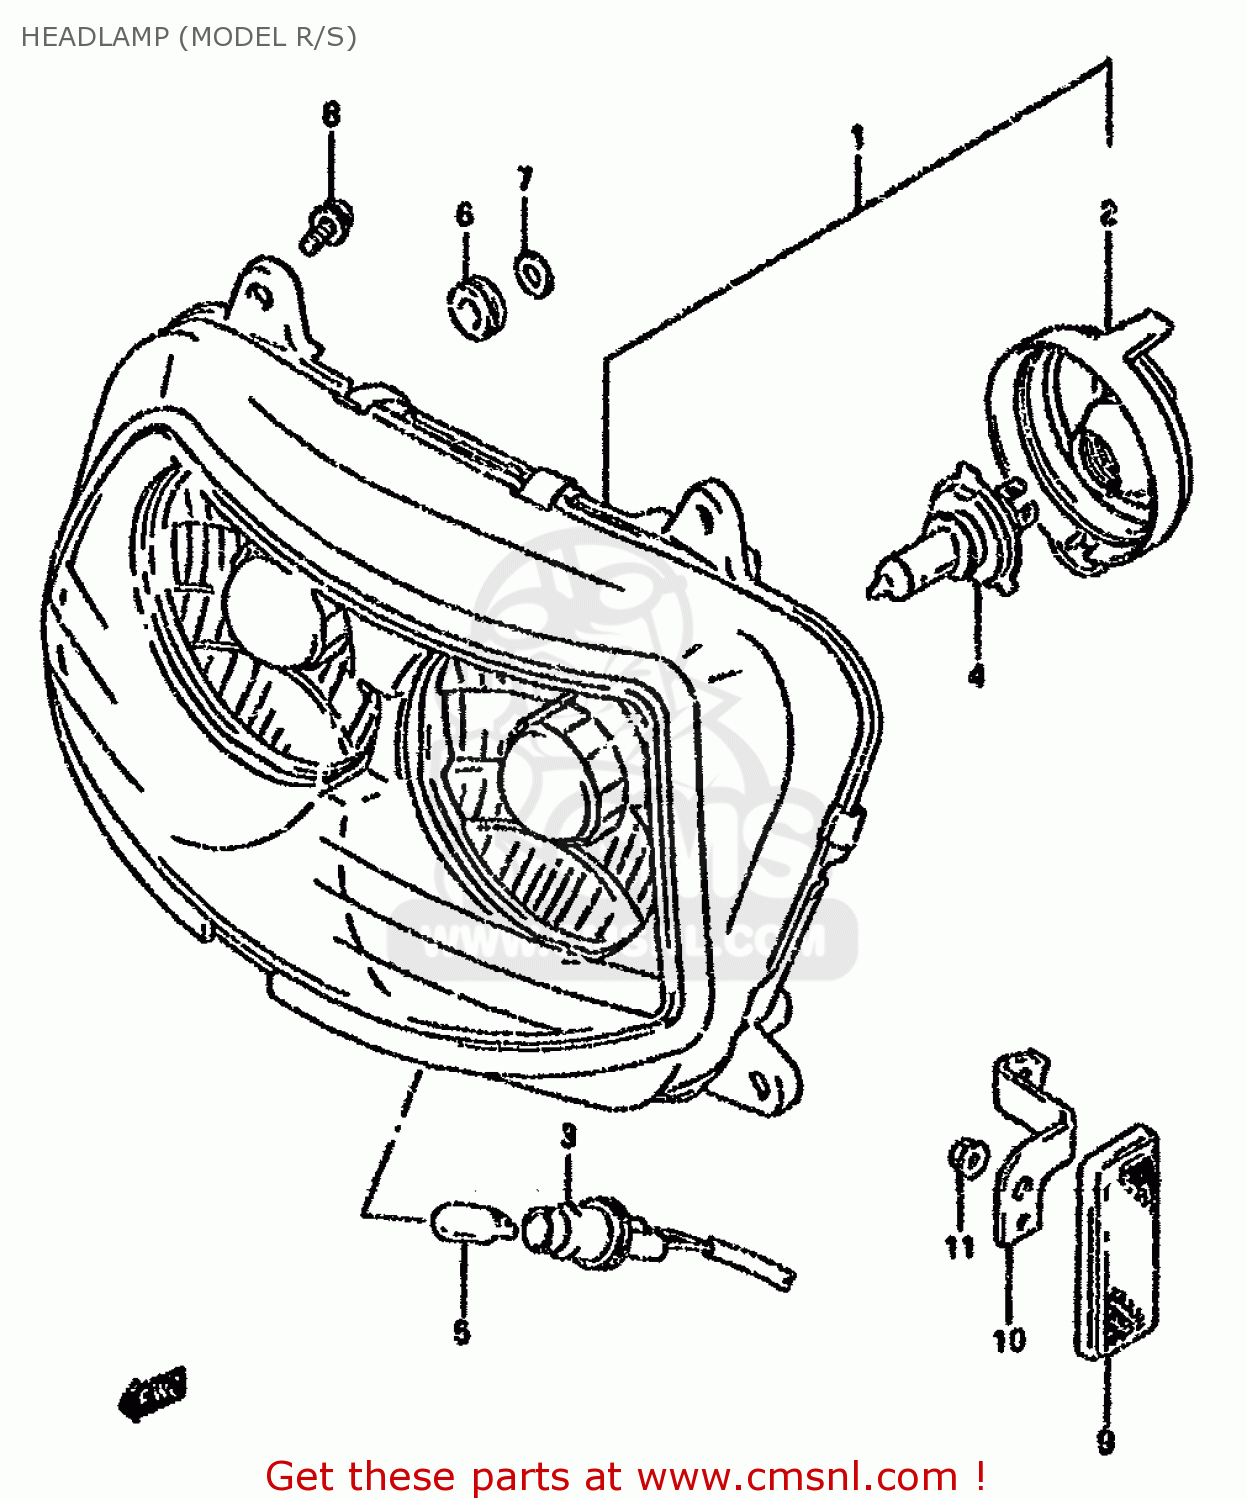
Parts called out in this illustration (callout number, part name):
1	HEADLAMP ASSY
2	COVER,SOCKET
3	SOCKET
4	BULB(12V60/55W,H4)
5	BULB(12V5W)
6	CUSHION
7	WASHER(5.5X16X1.2)
8	SCREW,SIDE HOL
9	SCREW
10	BRACKET,FR SIDE RR,R
11	NUT
12	SOCKET ASSY
13	CUSHION
14	WASHER (4X16X1.2)
15	SCREW
16	REFLECTOR,REFLEX FR
17	BRACKET,FR SIDE RR,R
18	NUT
